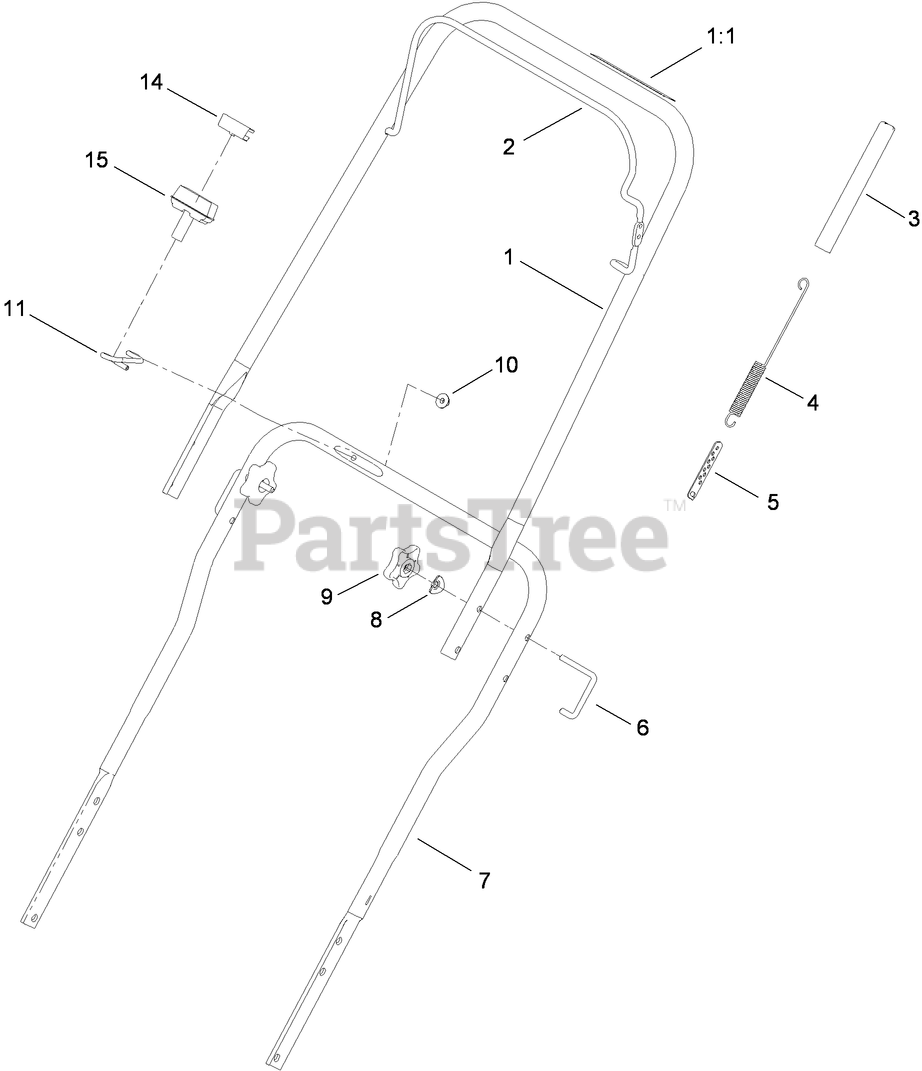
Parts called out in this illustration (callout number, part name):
1	UPPER HANDLE ASM
1:1	DECAL-DRIVE, ROTOR
2	BAIL-CLUTCH
3	COVER-SPRING
4	SPRING-EXTENSION, CLUTCH
7	HANDLE-LOWER
8	WASHER
9	KNOB-HANDLE
10	NUT-HF
11	GUIDE-ROPE
14	CLIP-STARTER
